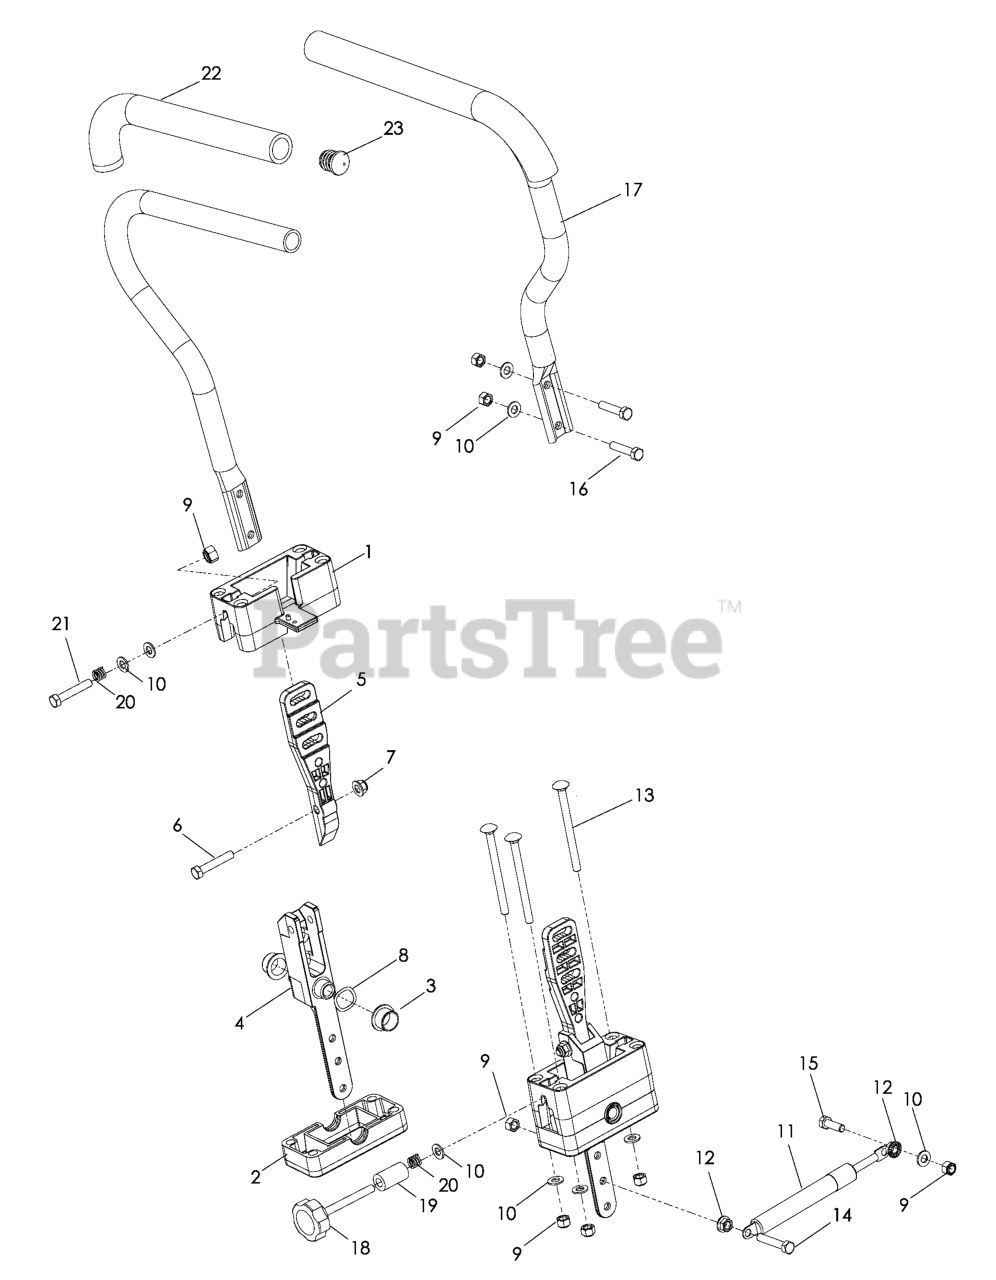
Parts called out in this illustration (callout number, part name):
1	BLOCK, UPPER
2	BLOCK, LOWER
3	BEARING, FLANGE
4	PIVOT.SECTION.DRIVE.CONTROL
5	MOUNT, DR CNTRL HANDLE
6	HCS 5/16C X 1 3/4
7	5/16-18 NYLOC FLANGE NUT
8	WASHER, .825 X 1.087, WAVE
9	NUT 5/16 NYLOC
10	FLAT WASHER 5/16 SAE
12	NUT 5/16C WHIZ
13	RHSNB 5/16-18 X 4 GR 5 ZD
14	HCS 5/16-18X1-3/4 TPBLT
15	HCS 5/16C X 1
16	CAPSCREW 5/16 X 1/1/2 HEX HEAD
17	LEVER.DRIVE.W/GRIP
19	DECK LIFT SPACER
21	HCS 5/16-18 X 2 TPBLT GR 5 ZD
22	GRIP, FOAM (GROUND) 15
23	END PLUG 15/16 (BLACK)
